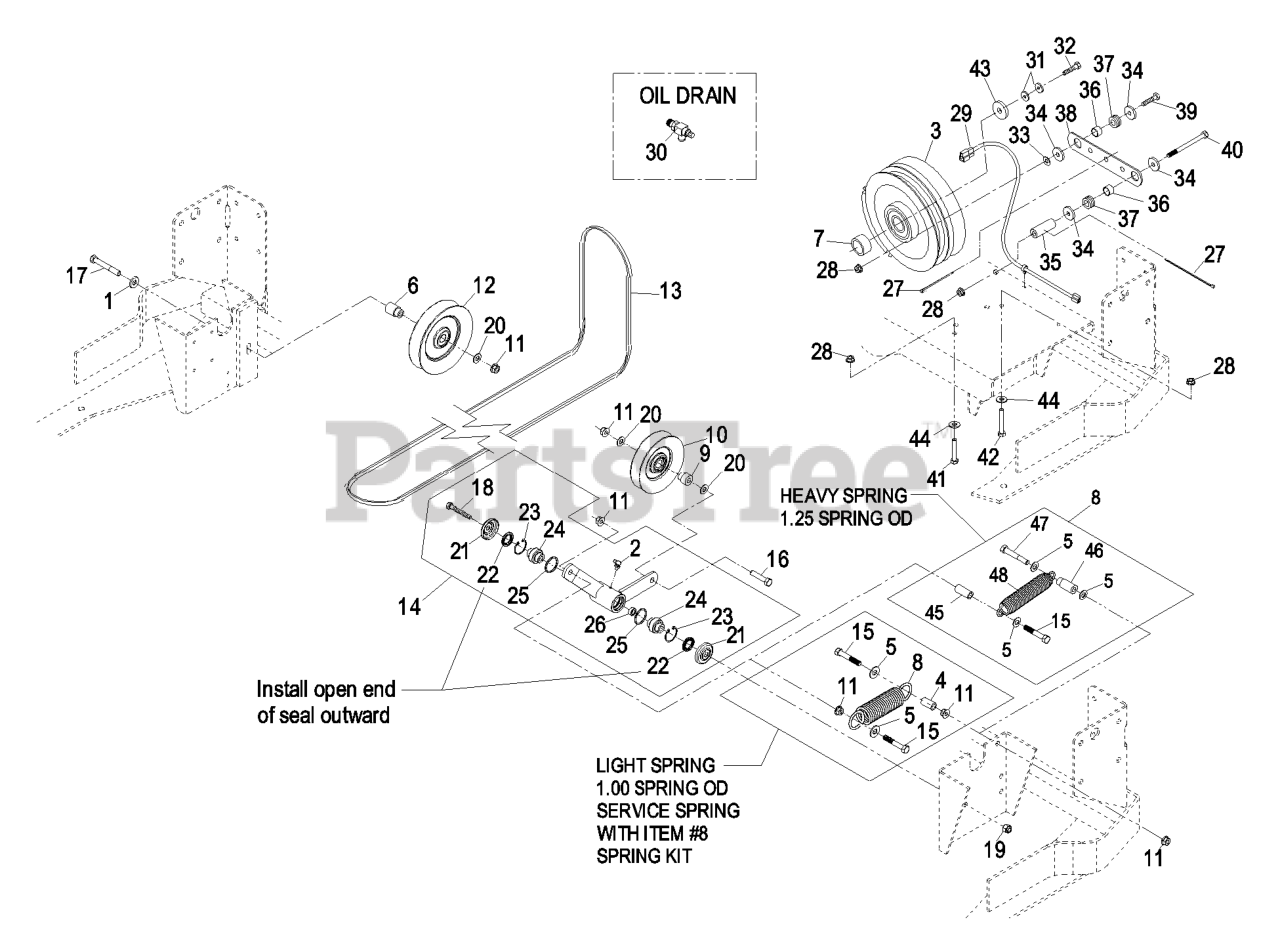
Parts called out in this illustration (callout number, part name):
1	WASHER-BELLEVILLE
2	FITTING-GREASE, 90 DEG
5	WASHER-FLAT
6	BUSHING-IDLER
9	BUSHING-IDLER
10	PULLEY-IDLER
11	NUT-HHF, WHIZ
12	PULLEY-IDLER
13	BELT-V B 118.75
14	KIT,MULE IDLER LZ
15	SCREW-HH
16	SCREW-HH
17	SCREW-HH
18	SCREW-HH
19	NUT-LOCK, NI
20	WASHER-FLAT
21	GUARD-TOP
22	SEAL-LIP, SINGLE
23	RING-SNAP
24	BEARING-SPHERICAL
27	TIE-PLASTIC
29	KIT,CLUTCH JUMPER HARNESS
30	VALVE-OIL DRAIN
31	WASHER-SPRING
32	SCREW-HH
33	WASHER-FLAT
35	SPACER-ANCHOR, CLUTCH
37	GROMMET
38	STRAP-CLUTCH, BRAKE
39	SCREW-HH
40	SCREW-HH
41	SCREW-HH
42	SCREW-HH
43	WASHER-CLUTCH
44	WASHER-SPRING
45	BUSHING-LEVER, LIFT
47	BOLT-CARR
